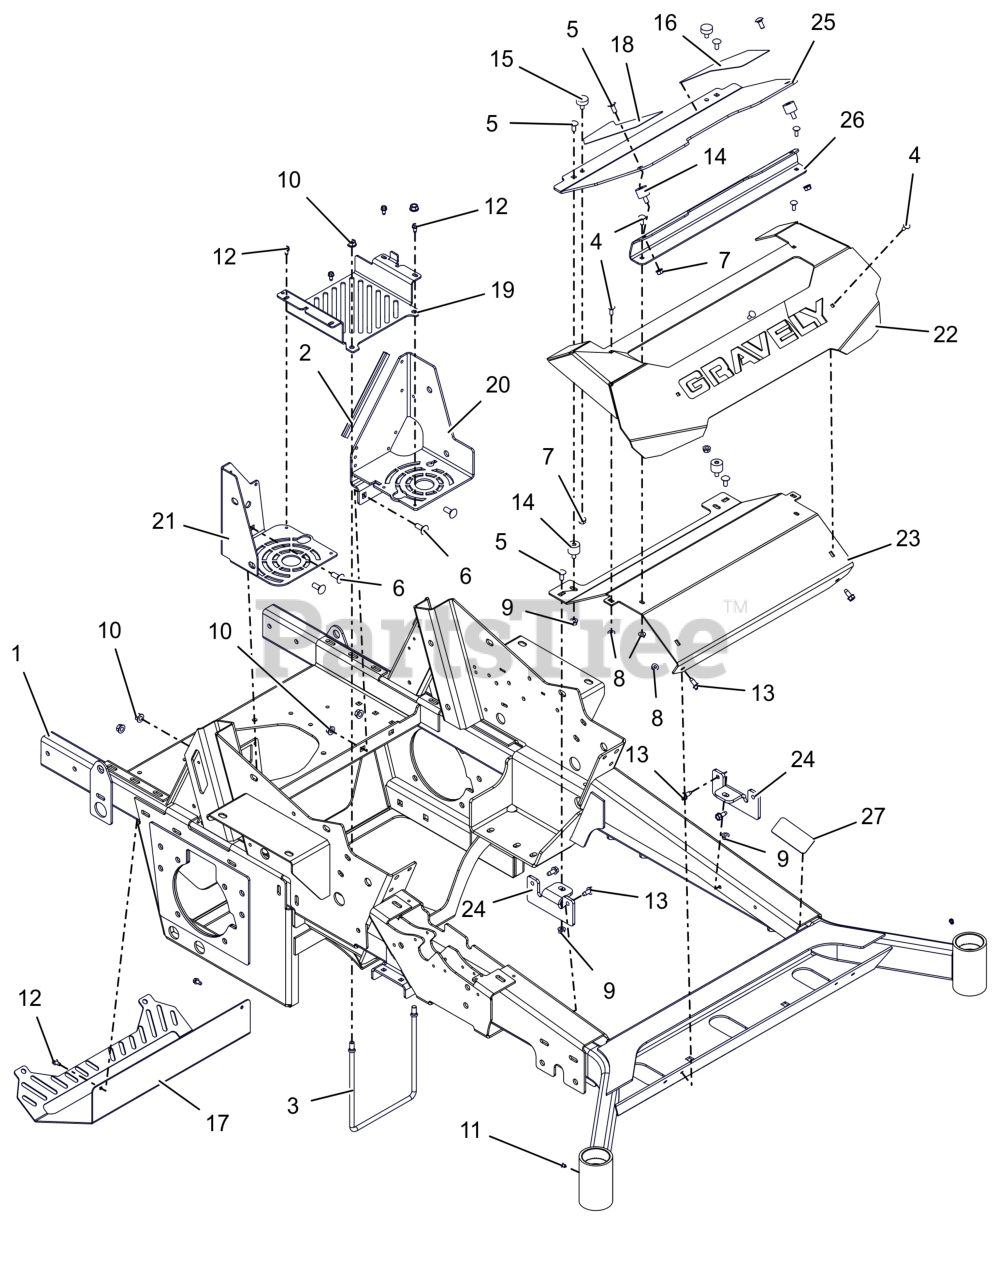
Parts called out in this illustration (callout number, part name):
1	WLDMT, MACH ONE, 72" FRAME (RED)
2	STRIP, COWL
3	ROD, BRAKE MTG
4	BLT, RHSN .25-20X.750 G5 ZCC
5	BLT, RHSSN.31-18X.750 G5 ZCC
6	BLT, RHSN .38-16X1.00 G5 ZCC
7	NUT,SPNLK-FLG .31-18 G5 ZCC
8	NUT-LK-CTR-FLG .25-20 ZC120
9	NUT,LK-CTR-FLG .31-18 GF ZCC
10	NUT-LK-CTR-FLG .375-16 GF ZCC
11	FTG, .25-28 FLUSH MNT GREASE
12	SCR-TAP .25-20X.50 HWH ZCC
13	SCR,TAP .312-18X.75 HWH TR ZCC
14	BUMPER,STUD MNTD W/FEMALE INSR
15	BUMPER, RUBBER
16	KIT, PT300-600 ANTI-SKID Tape
17	GUARD, MUFFLER (BLACK)
18	KIT, PT300-600 ANTI-SKID Tape
19	TRAY- BATTERY
20	GUSSET-LH BATTERY TRY/ROPS-RED
21	GUSSET- FAN GUARD/ROPS - RED
22	BMPR-PT300-500 FRT FTRST/ -RED
23	BRKT-FRT BUMPER MTG/BACKER-BLK
24	BRKT- FOOTREST MTG
25	FOOTREST, PT300-500 (RED)
26	BRKT, FOOTREST SUPPORT (BLK)
27	KIT, PT300-600 ANTI-SKID Tape
